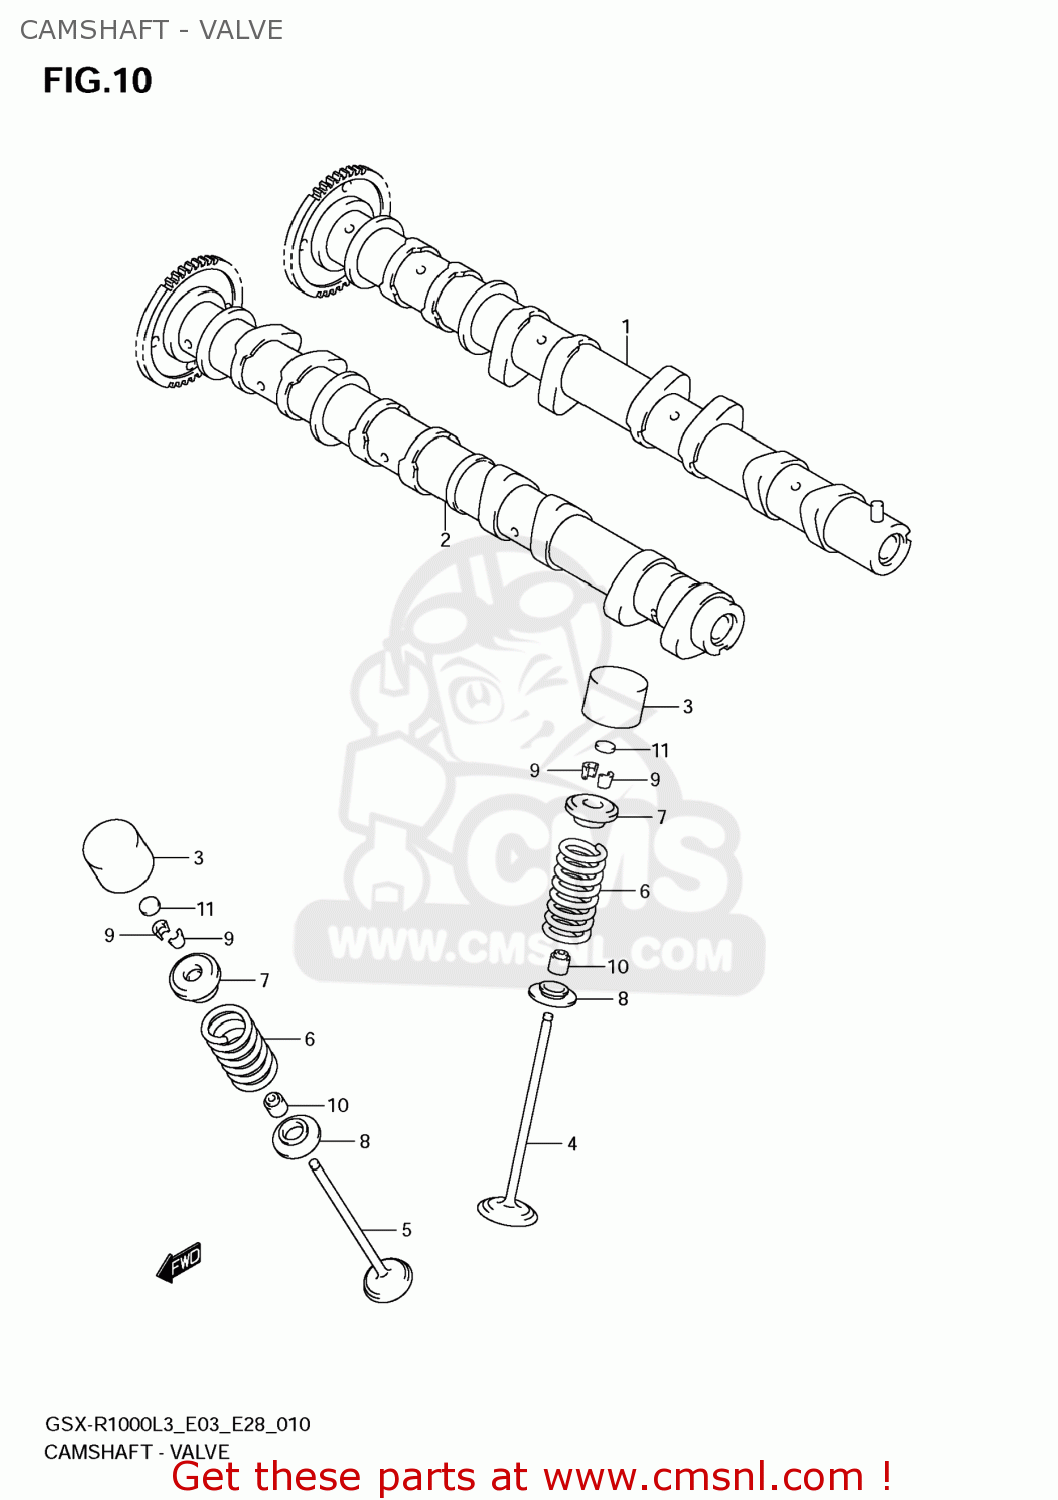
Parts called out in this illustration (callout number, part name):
1	CAMSHAFT,INTAKE
2	CAMSHAFT,EXHAUST
3	TAPPET
4	VALVE,INTAKE
5	VALVE,EXHAUST
6	SPRING SET,VALVE
7	RETAINER,VALVE SPRING
8	SEAT,VALVE SPRING
9	COTTER VALVE
10	SEAL,OIL(4.5X10X8)
11	SHIM,TAPPET
12	SHIM SET,TAPPET
13	CASE,TAPPET SHIM
